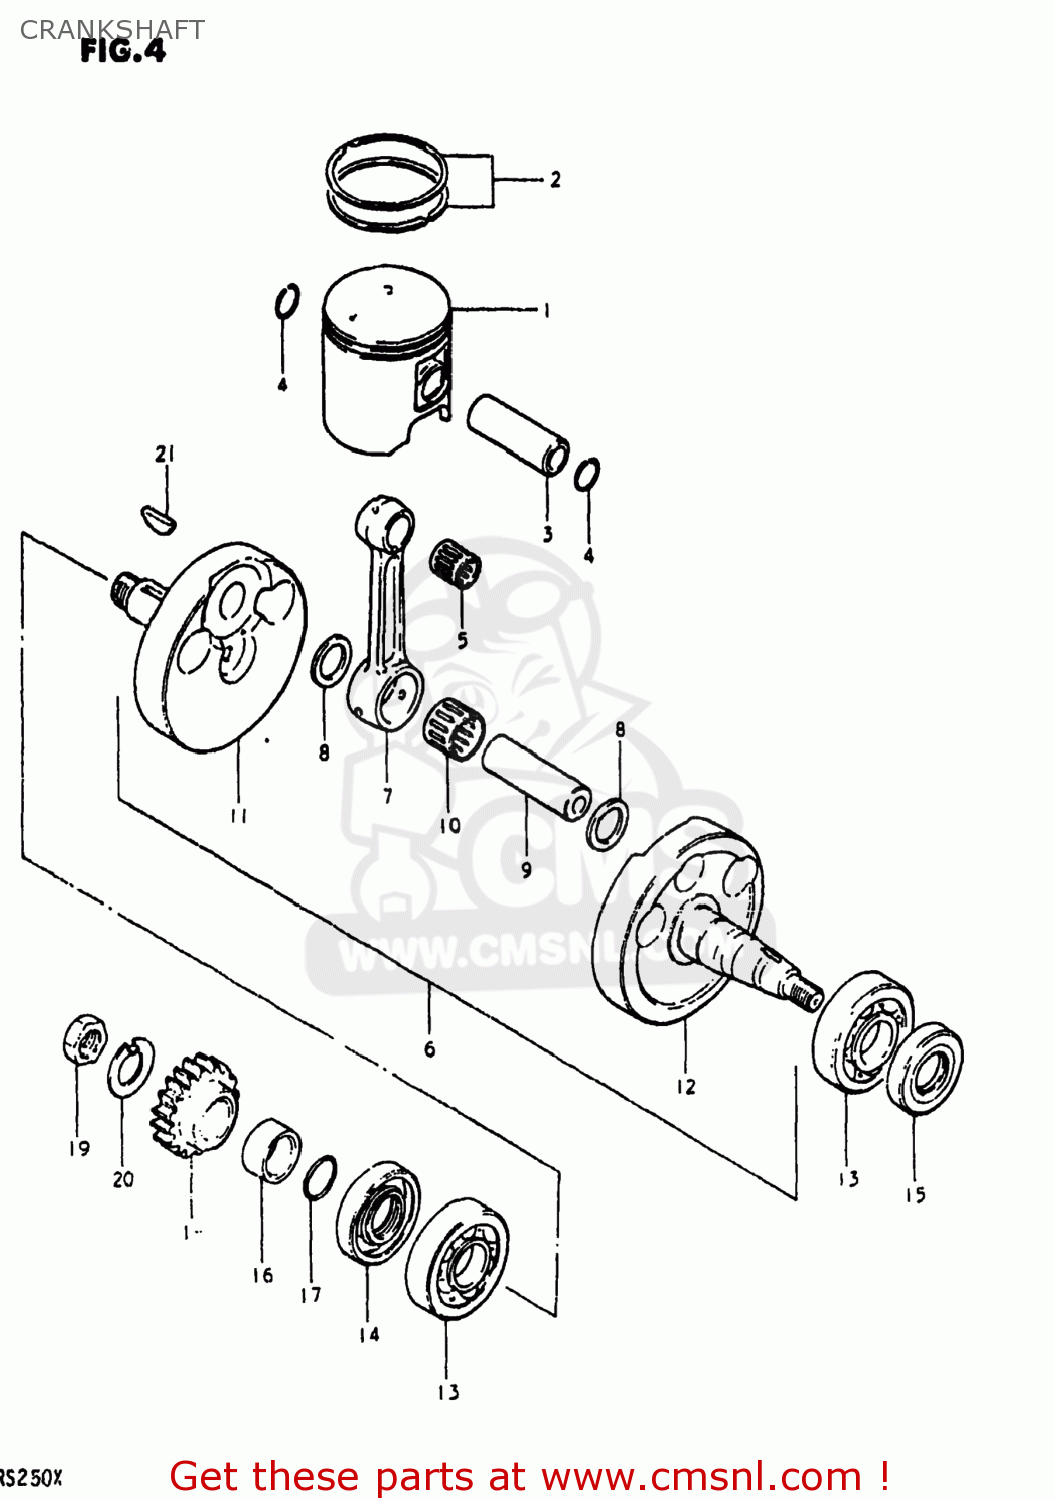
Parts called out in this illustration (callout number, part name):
1	PISTON
2	RING SET,PISTON
3	PIN,PISTON (18MM)
4	CIRCLIP
5	BEARING(18X23X22)
6	CRANKSHAFT ASSEMBLY
7	ROD,CONNECTING
8	WASHER(24X29X1.5)
9	PIN,CRANK
10	ROLLER BEARING (24X30X1
11	CRANKSHAFT
12	CRANKSHAFT,LEFT
13	BEARING
14	SEAL,OIL(32X52X8.4)
15	SEAL,OIL(24X50X9)
16	SPACER
17	O RING(D:2.4,ID:19.8)
18	GEAR,PRIMARY DRIVE
19	NUT
20	WASHER
21	KEY
